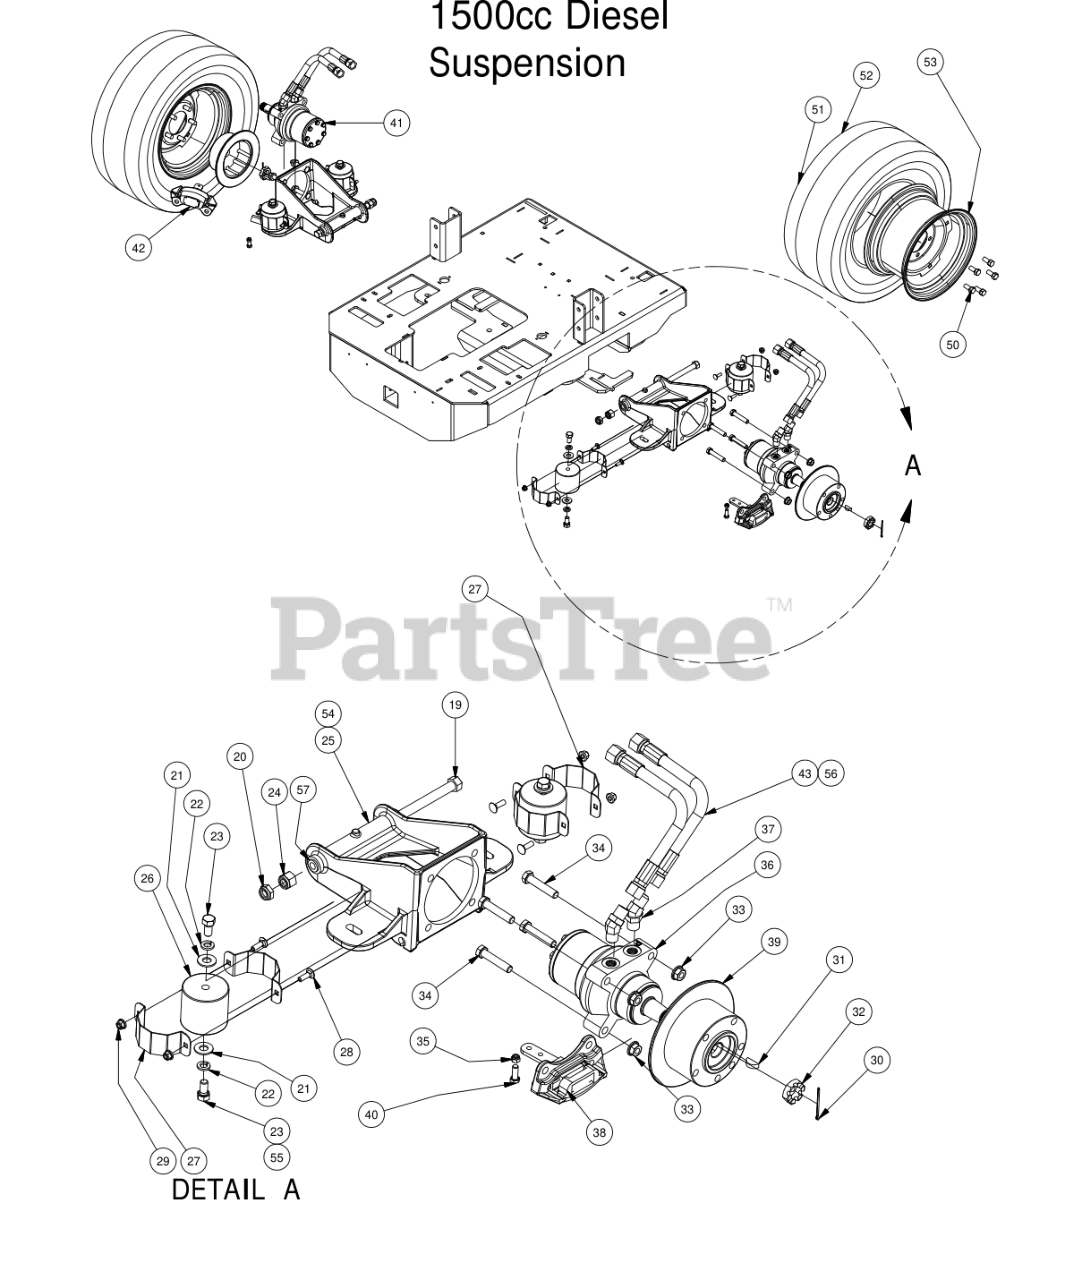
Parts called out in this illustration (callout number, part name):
1	Diesel Back Pump Cover 2008 Bottom
2	Back Cover Hinge Bracket
3	Diesel Back Pump Cover 2008 Top
4	Diesel Hood 4 Cyl
5	5/16" x 1" Carriage Bolt
6	.360 ID Plastic Washer
7	1/4" x 5/8" BS C/S 18-8 SS
8	5/16-18x3/4 carriage bolt
9	5/16" Flange Nut
10	1/4 Nylock Nut
11	5/8 Round Insert
12	5/16" x 1" Bolt
13	5/16-18 Nylock Insert Locknut
14	5/16" Knob
15	5/16" x 1 1/4" Carriage Bolt
16	1/4" x 1 1/2" Self Tapping Screw
17	1/4" Flat Washer
18	8" Rubber Bumper
19	5/8"x10" Hex Bolt (Grade8)
20	5/8" Nylock (1/2 Jam)
21	1/2" Washer (Grade 8)
22	1/2" Lock Washer
23	1/2" x 1" Hex Bolt
24	5/8 Std NC Nylock Nut
25	60 Suspension kit Wheel Motor
26	Vibration Mount-Blue Dot
27	Isolator Band Clamp
28	5/16" x 1" Carriage Bolt
29	5/16" Nylon Flange Nut
30	1/8x2-1/4 cotter pin Zinc
31	Woodruff Key
32	1" Castle Nut for Wheel Motor
33	1/2" Flange Nut
34	1/2" x 2 1/2" Hex Bolt
35	5/16-18 Nylock Insert Locknut
36	18cc Parker Wheel Motor- Right
37	45 Degree Wheel Motor Fitting -6802-10-10
38	XP/AOS Right Brake Caliper
39	Brake Disk
40	3/8" x 1" Hex Bolt
41	18cc Parker Wheel Motor- Left
42	XP/AOS Left Brake Caliper
43	26" Hose Assembly with Adaptors
44	5/8" x 2 1/2" Grade 5 Hex Bolt (Coarse)
45	5/8 Std NC Nylock Nut
46	5 V Idler Pulley - BCVI-81
47	5/8" x 1/" Collar W/One Set Screw
48	Steel Pump Cover Latch
49	10-24 X 5/8 BS Button Head Bolt
50	1/2-20 x 1-1/2 Lug Bolts Zinc
51	26 x 12.00- 12 Tire and Orange Wheel Assembly
52	26 x 12.00 12 Tire
53	12 x 10.5 Wheel AOS Rear
54	72 Suspension Kit Wheel Motor
55	1/2-13 1-1/4 Hex bolt Only On 60" Suspension Kit Wheel Motor
56	26" Hose Only
57	Brass Bushing
58	10-24 Nylock Locknut
